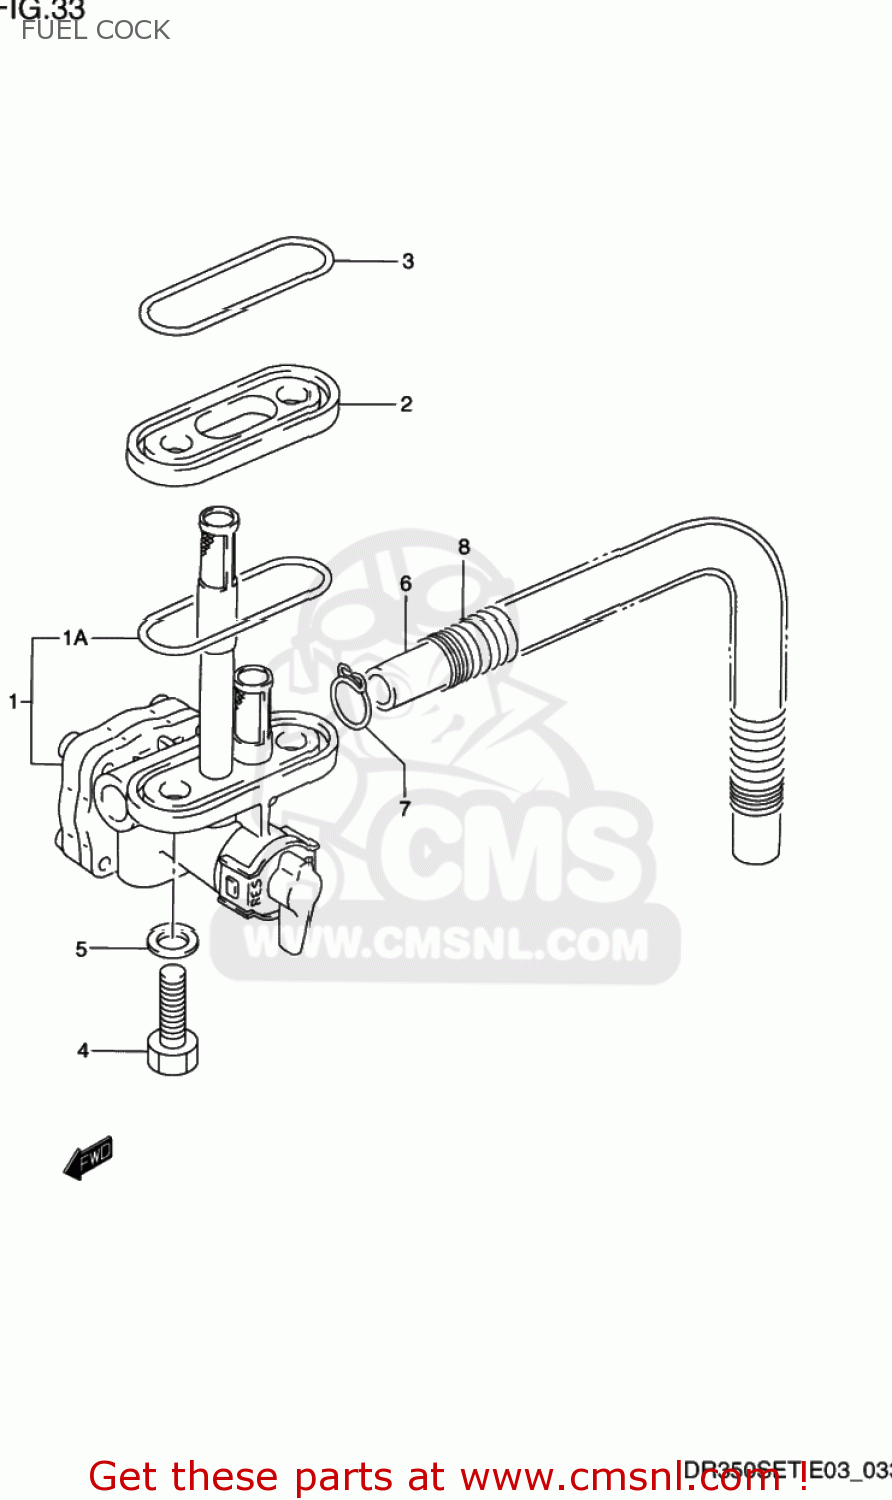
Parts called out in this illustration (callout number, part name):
1	COCK ASSY,FUEL
1A	GASKET,JOINT (NAS)
2	SPACER,FUEL COCK
3	GASKET,FUEL COCK (NAS)
4	BOLT(6X20)
5	GASKET(6.4X11.5X0.8) (NAS)
6	HOSE(7X10.2X600)
7	CLIP
8	SPRING
9	CLAMP(L:45)
